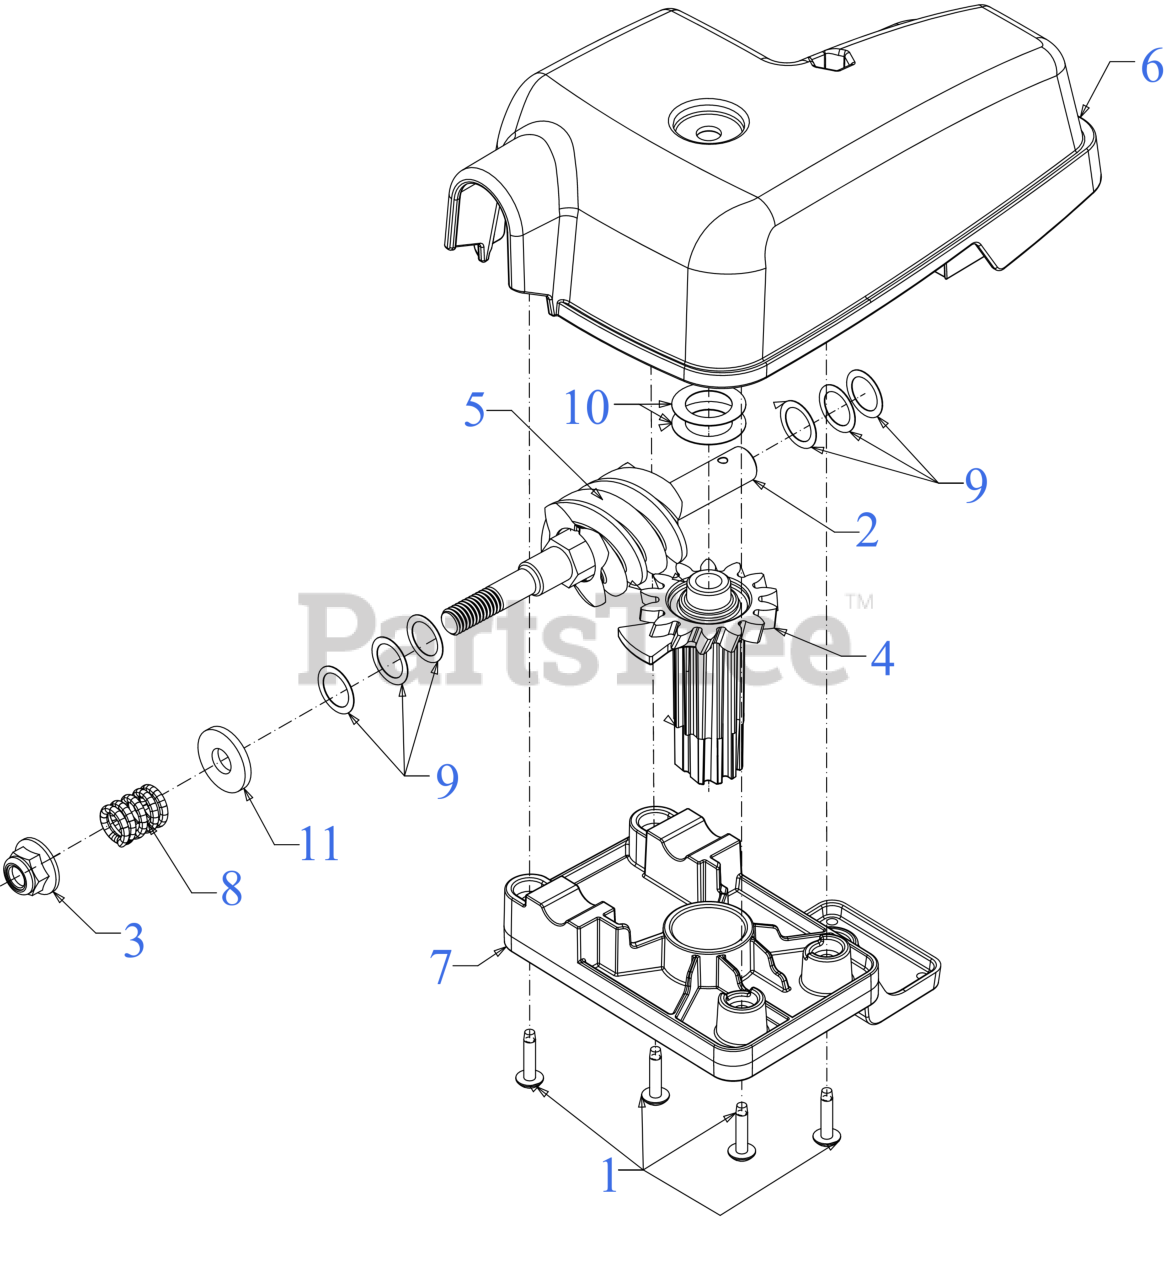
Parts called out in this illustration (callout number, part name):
1	SCREW 8-16 x 3/4
2	HEX SHAFT WORM DRIVE .500/2W
4	HELICAL GEAR-14T
5	CHUTE GEARBOX WORM GEAR
6	CHUTE CONTROL GEAR COVER (2WAY)
7	CHUTE HOUSING GEAR BASE
8	COMPRESSION SPRING
9	FLAT WASHER .504 X.700X.010
10	SHIM WASHER .632X1.000X.010:HD
